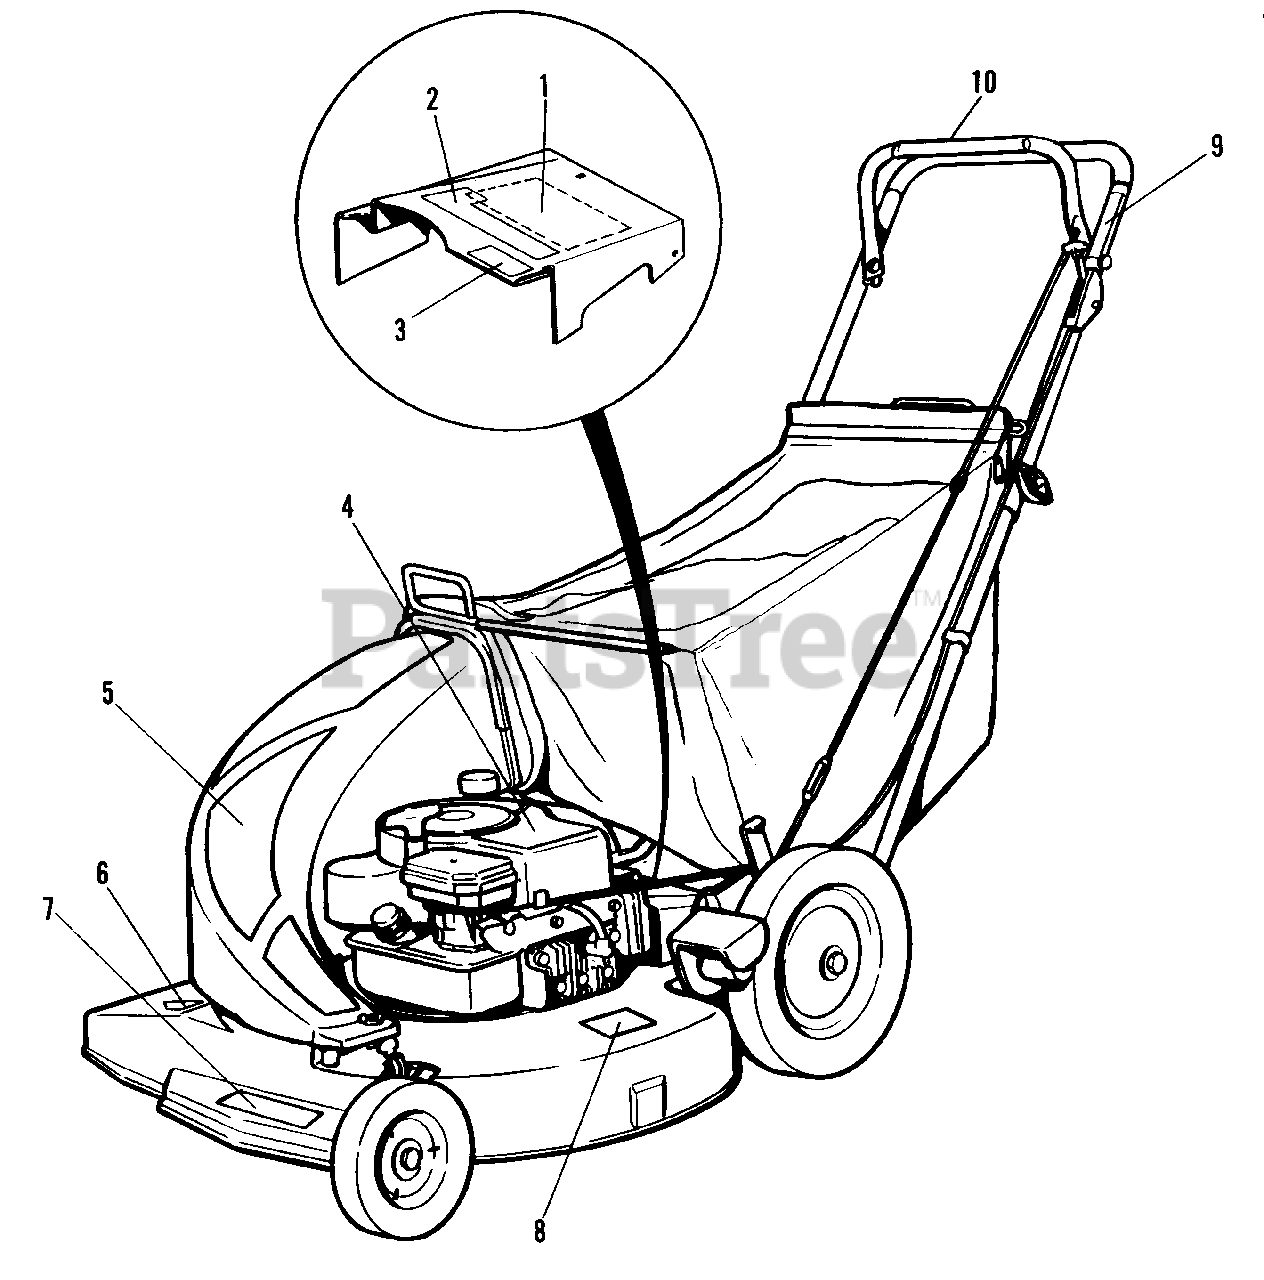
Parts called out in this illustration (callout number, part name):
1	DECAL, Speed Range
2	DECAL, Simplicity. 1221
3	DECAL, Hot Surface
4	DECAL, Engine Shroud
5	DECAL, Stripe, Chute
6	DECAL, Danger
7	DECAL, Simplicity
8	DECAL, Caution
9	DECAL, Handle
10	Decal, Control
